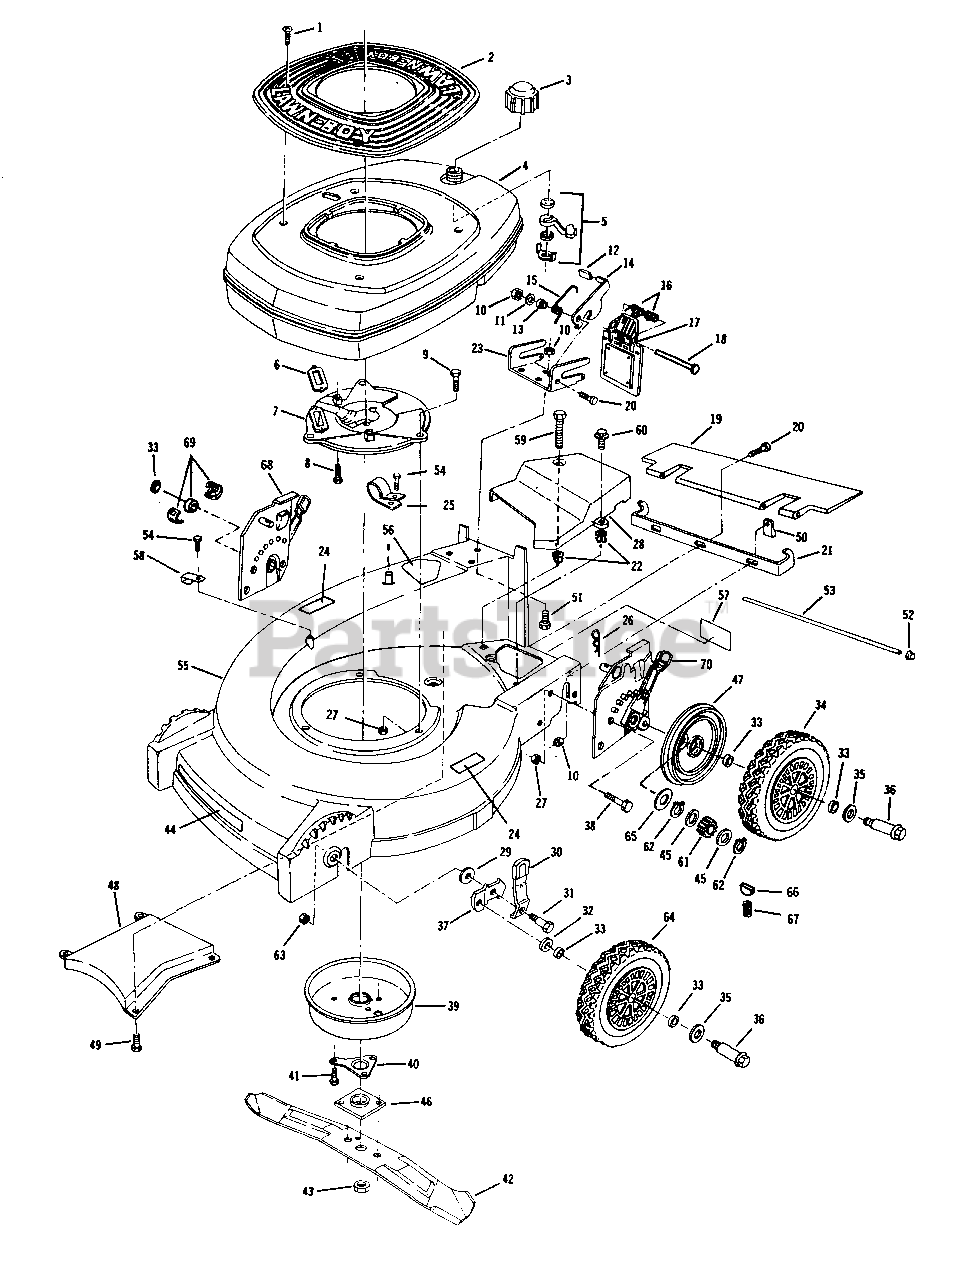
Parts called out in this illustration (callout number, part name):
1	Screw
2	Cover-Shroud
4	Shroud-Engine
5	Fuel Shut-Off Assembly
6	Gasket-Exhaust
7	Plate-Muffler
8	Screw-Muffler Plate to Block
9	Screw-Muffler Plate to Housing
10	Nut-Latch Brk't. and Trailing Shield
11	Washer
12	Knob-Latch
13	Stepped Spacer
14	Catch-Bag
15	Spring-Latch
16	Spring
17	Door
18	Rod
19	Shield-Trailing
20	Screw-Latch Bracket and Trailing Shield
21	Bracket-Bag Hanger
22	Grommet
23	Hinge Plate
24	Decal-Ht. Adj.
25	Clamp-Cable and Primer Hose to Housing
26	Pin
27	Nut-Ht. Adj. to Hous. and Muff. Plate to Hous.
28	Cover Belt
29	Washer-Wheel Ht. Adj.
30	Knob and Spring Assembly
31	Bolt-Shoulder
32	Washer
33	Washer-Felt
34	Wheel and Tire Assembly 8" S.P.
35	Washer-Wheel Bolt
36	Bolt-Shoulder Wheel
37	Bracket-Wheel Ht. Adj.
38	Bolt-Height Adjuster Assembly
39	Muffler Cover Assembly
40	Support-Crankshaft
41	Screw-Muffler to Muffler Blt.
42	Blade-20"
43	Nut
44	Decal-Manual Restart
45	Spacer
46	Collar and Plate Assembly
47	Cover-Wheel
48	Baffle
49	Screw
50	Clamp-Rod
51	Screw-Truss Head
52	Nut-Rod
53	Rod-Trailing Shield
54	Screw-Clamp to Housing
55	Housing-20" Assembly
56	Decal-Blade Contact Warning
57	Decal-Caution
58	Clamp-Cable to Housing
59	Screw-Hex Hd.
60	Screw-Shoulder Idler
61	Pinion
62	Retaining Ring
63	Nut-Wheel Ht. Adj.
64	Wheel and Tire Assembly 8"
65	Washer
66	Key
67	Spring
68	Height Adjuster Assem.-R.H.
69	Bearing and Retainer Ass'y.
70	Height Adjuster Assem.-L.H.
